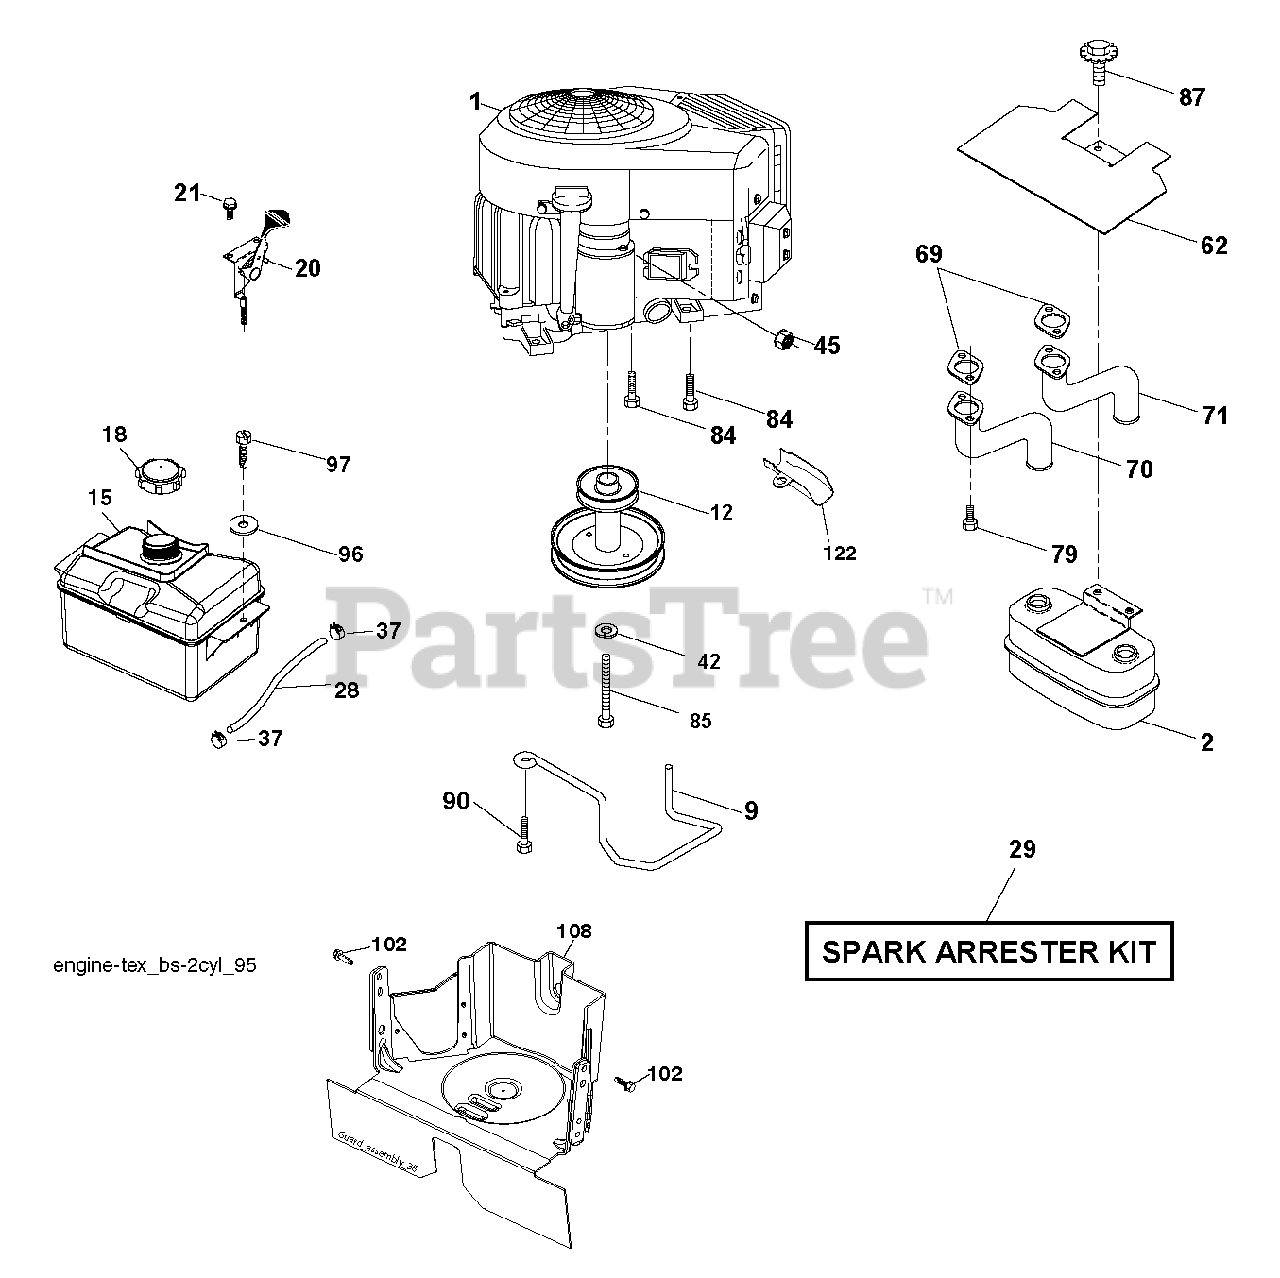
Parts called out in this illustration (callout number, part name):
2	MUFFLER.TWIN.CYL.LOW.TONE
9	KEEPER.BELT.ENGINE.4.2
12	PULLY ENGINE
18	CAP ASM.FUEL.2.25"FR.
20	CONTROL.TH/CK.COBRA.B&S.TWN.
21	SCREW.#10 X 0.750.BOS THREAD
28	LINE.FUEL.20
29	ARRESTER SPARK (OPTIONAL)
37	HOSE CLAMP
42	LOCKWASHER
45	NUT
62	SHIELD.HEAT.MUFFLER
69	REPL BY 532 27 22-93
70	TUBE MANIFOLD LH
71	EXHAUST TUBE RH
79	SCREW.SOCKET.HEAD.5/16-18
84	SCREW.3/8-16
85	BOLT HEX 7/16-20X4-1/4"
87	BOLT, 5/16-18 X 1 3/4
90	SCREW 3/8-16X1
96	WASHER
97	SCREW HEXWSHR 1/4-20X3/4
102	SCREW 5/16-18X1
122	EXTENSION DRAIN OIL
